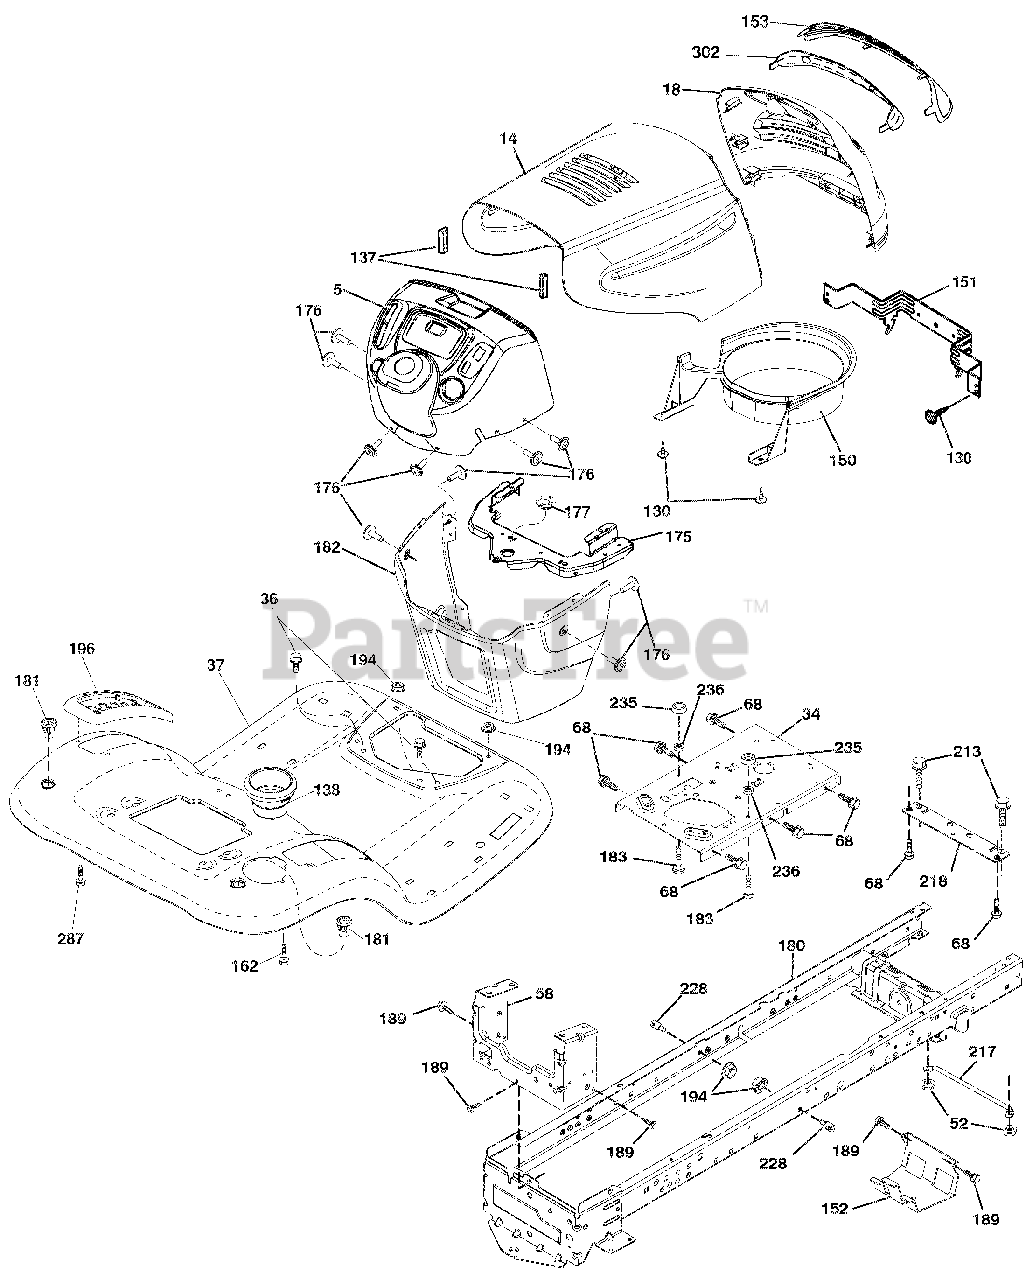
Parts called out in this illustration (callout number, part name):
5	DASH.P/L TEX.CBL CL.N/CHK.428
14	HOOD.PNT.ELITE.SPL-TP.N-SKIRTS
18	GRILLE ASM.ELITE BASIC.ARIENS
34	PLATE.ENGINE.WELDED.CHASSIS
36	SCREW.5/16-18X3/4.SMGML.TAP/R
37	FENDER.TLT.FS.W/CUPHLD.422
52	Nut, Hex, Crownlock 5/16-18
58	DRAWBAR.UPPER.2PC.SML.FENDER
68	SCREW.THDROL.5/16-18 X 1/2TYTT
137	BUMPER.HOOD.LARGE. 1.75"
138	CUPHOLDER.TL.TEX.428
150	AIR DUCT.INTAKE.B&S/HONDA.
151	BRACKET.PIVOT.LASR/ELTE/HUSQLT
152	SHIELD.BROWNING.W/TEX
153	LENS.GRILLE.BASIC.BAR.LT.CLR.
162	SCREW.HEX.WSH.HI-LO.1/4X1/2UNC
175	CROSSMEMBER.LT
176	SCREW.#10-24X5/8.RND.QUDRX.GIM
177	BUSHING.STEERING.LT
180	CHASS.WLDMT.TL.12GA/2PC.18/22"
181	BUSHING.MNT.FEND.CRGO.BLK.TEX
182	DASH LOWER.LT.CCS
183	BOLT.FIN.HEX.5/16-18UNC X1-1/4
189	SCREW.5/16-18X3/4.SMGML.TAP/BL
194	Nut, Lock Hex Flange 5/16-18 u
196	CONSOLE ASM.DECKLFT.BL/RBT.TLT
213	Bolt, Hex Head 5/16-18 x 3/4
217	ROD.PIVOT.HOOD
218	X-PIECE.HOOD.STOP.NON/STEALTH
228	STUD.FASTNER.W/'D'ANTI-ROTATIO
235	SPACER.FENDER
236	NUT.CENTER LOCK.5/16-18 UNC
287	SCREW.HEX.WASHEAD.1/4-20 X 3/8
302	INSERT.LENS.REFL.BASIC.LT
